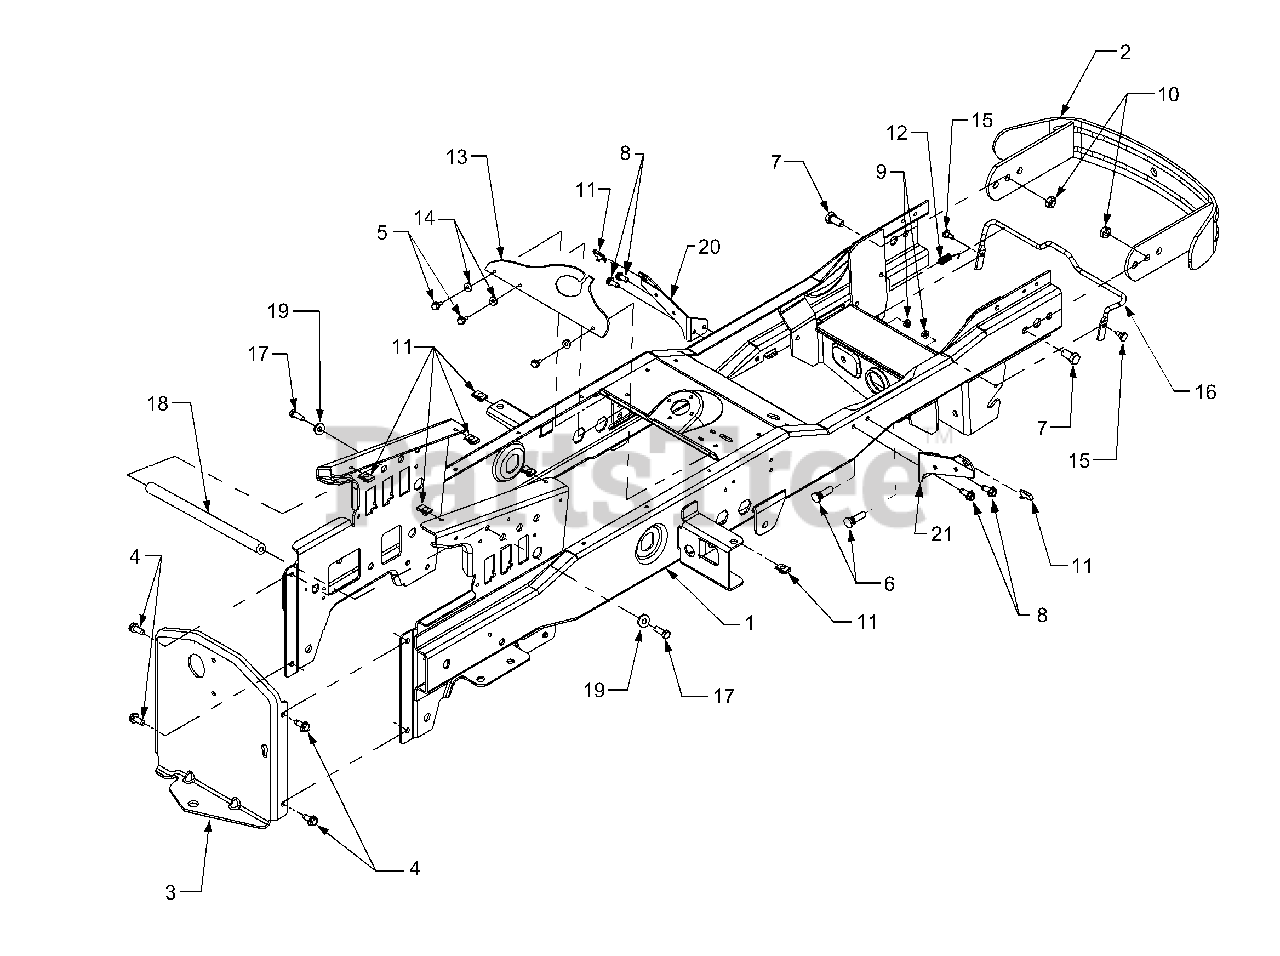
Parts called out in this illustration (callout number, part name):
1	Frame Assembly
2	Bumper, Front
4	Screw, Hex Wash. Hd. Tapp 3/8-16 x .75
5	Screw, Hex Wash. Hd. Tapp 1/4-20 x .5
6	Screw, Round Hd., 3/8-24
7	Screw, Hex Cap 1/2-13 x 1.0 GR5
8	Screw, Hex Wash. Hd. Tapp 5/16-18 x .75
9	Nut, Hex Flange Lock, 1/4-20
10	Nut, Hex Lock, 1/2-13
11	Speed Nut, U-Type, 5/16-18
12	Spring, Extension
13	Flap, Intk.
14	Washer, Flat, .283 x .75 x .030
15	Shoulder Screw, .312 x .18
16	Rod, Front Latch
17	Screw, Hex Cap, 5/16-18 x .875
17	Screw, Hex Cap, 1/4-20 x .75 GR5
18	Shaft, Frame Brace
18	Shaft, tank constraint
19	Washer, Flat, .344 x .75 x .12
19	Washer, lock, 1/4
20	Bracket, Running Board LH
21	Bracket, Running Board RH
